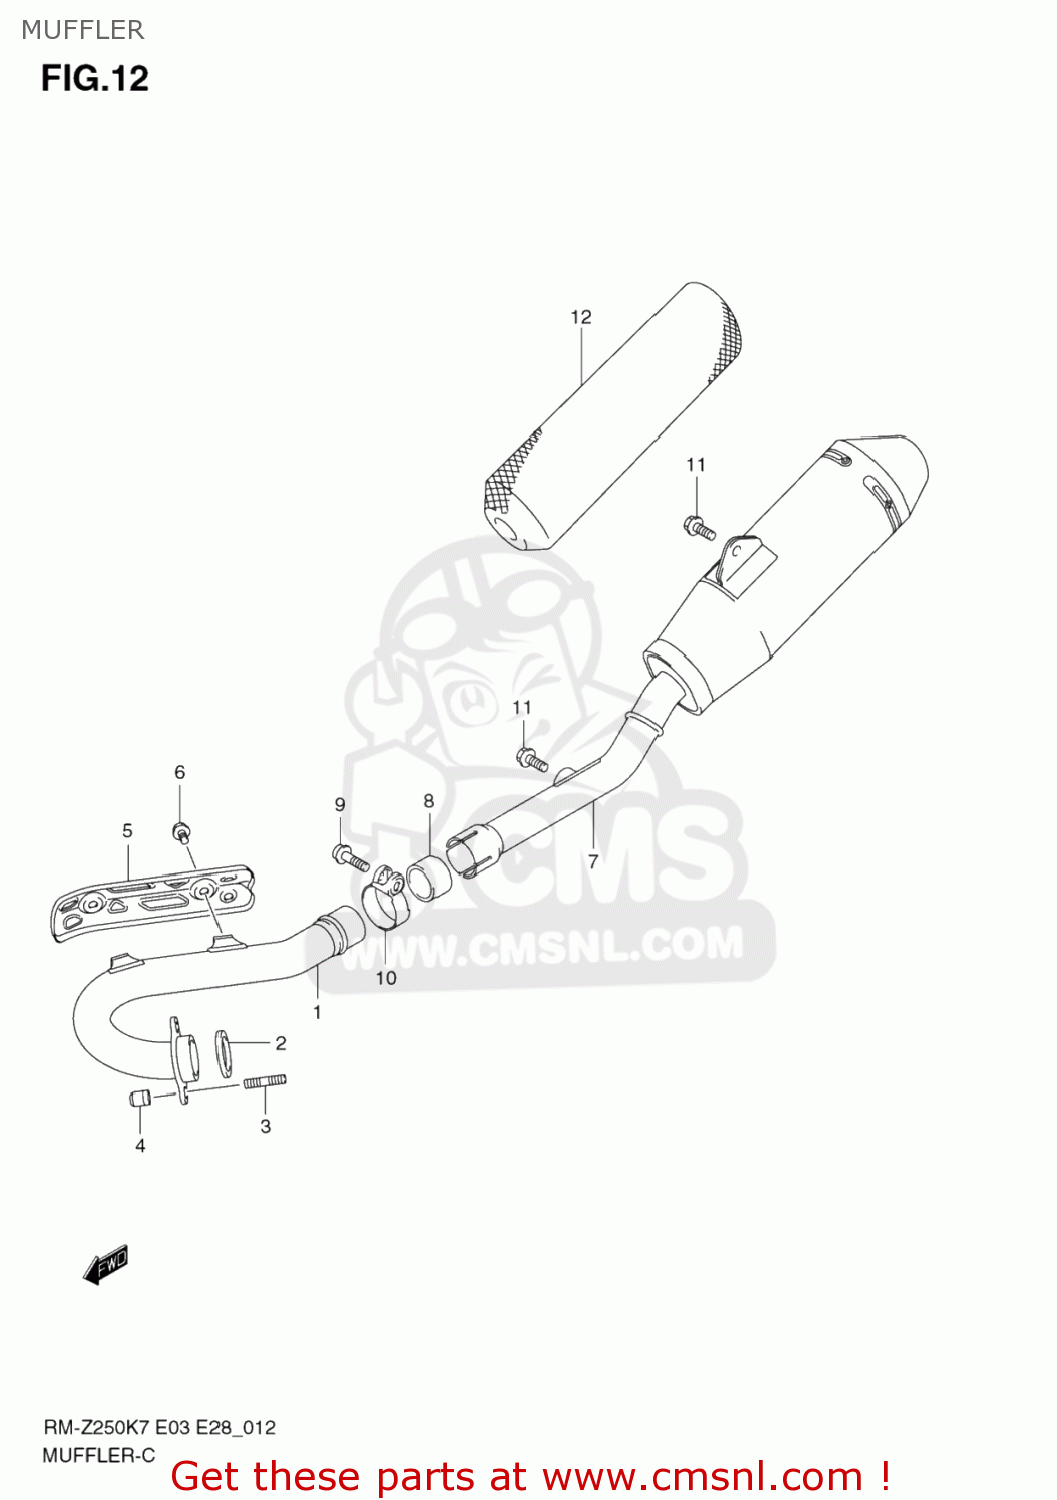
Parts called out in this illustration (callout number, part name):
1	PIPE,EXHAUST
2	GASKET,EXHAUST PIPE (NAS)
3	BOLT,STUD
4	NUT
5	COVER,EXHAUST PIPE
6	SCREW(6X10)
7	BODY,MUFFLER
8	CONNECTOR,MUFFLER JOINT
9	BOLT
10	CLAMP,CONNECTOR
11	BOLT(8X20)
12	SILENCER,MUFFLER
